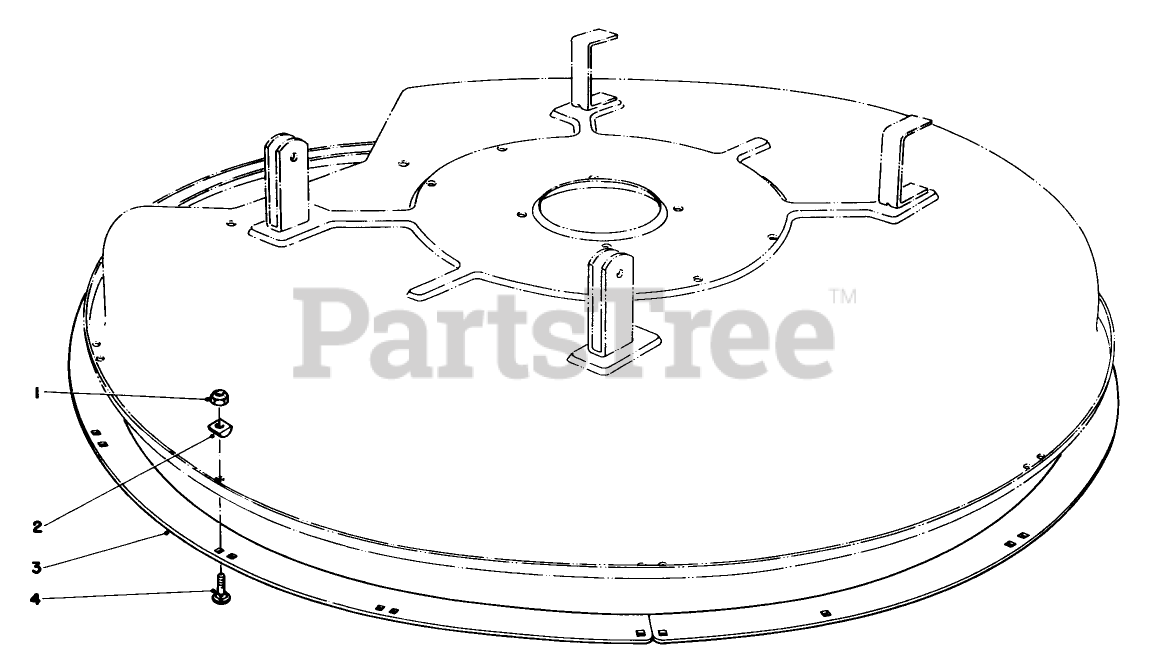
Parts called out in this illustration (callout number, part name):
1	NUT-LOCK, NI
3	DECK RING *B
4	BOLT-CARR
